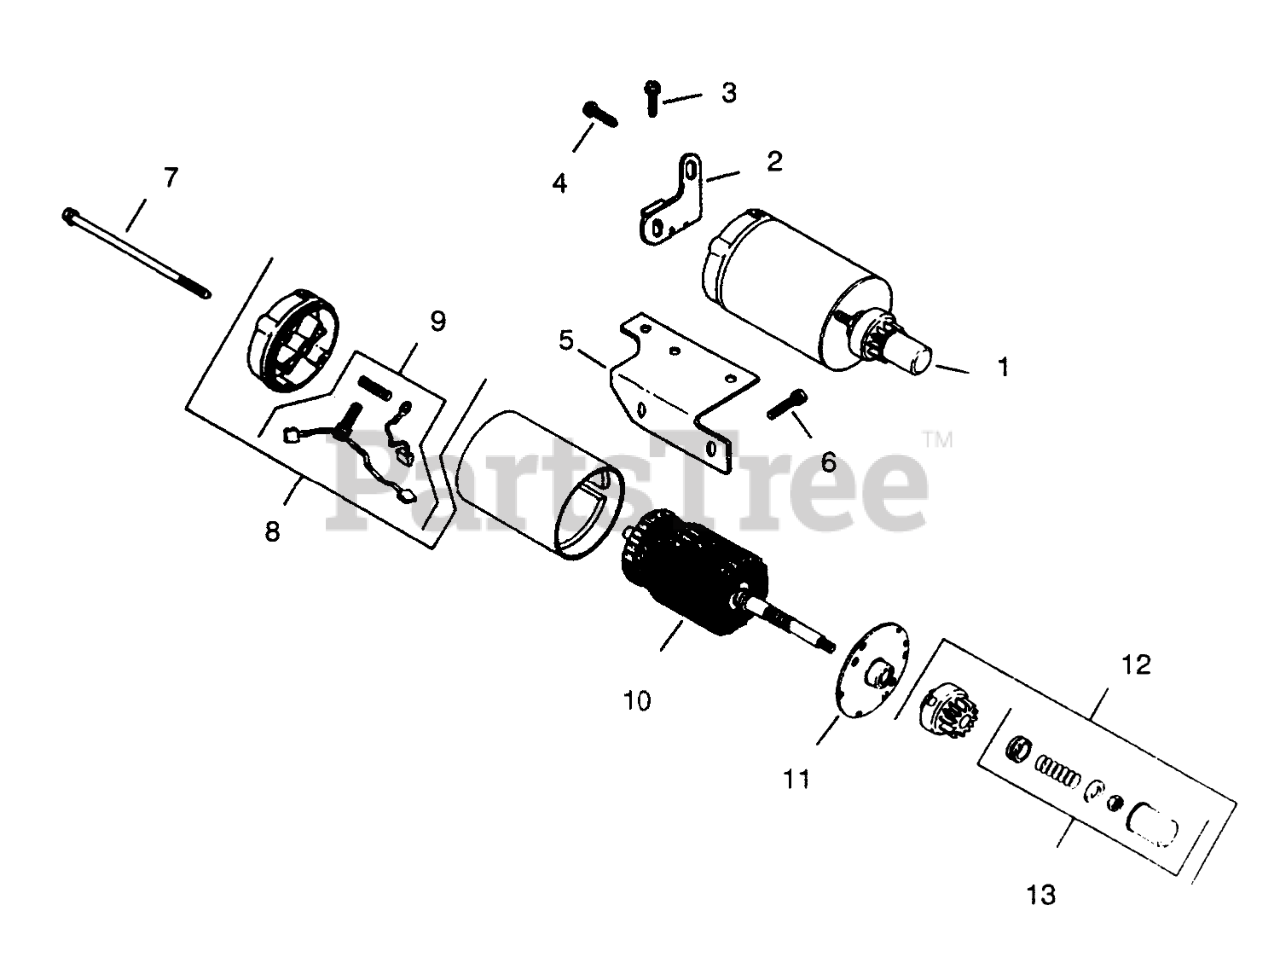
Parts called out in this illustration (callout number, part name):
1	Starter Assembly (Incl. Ref. # 9-15)
2	Brace-Starter Tail
3	Screw
4	Screw-Hex. Hd.
5	Bracket-Starter
6	Screw
8	End Cap Ass-y (Incl. Ref.#9)
9	Brush Kit
10	Armature
11	Cap-Drive End
12	Kit-Drive (Incl. Ref. #15)
13	Drive Parts Kit
